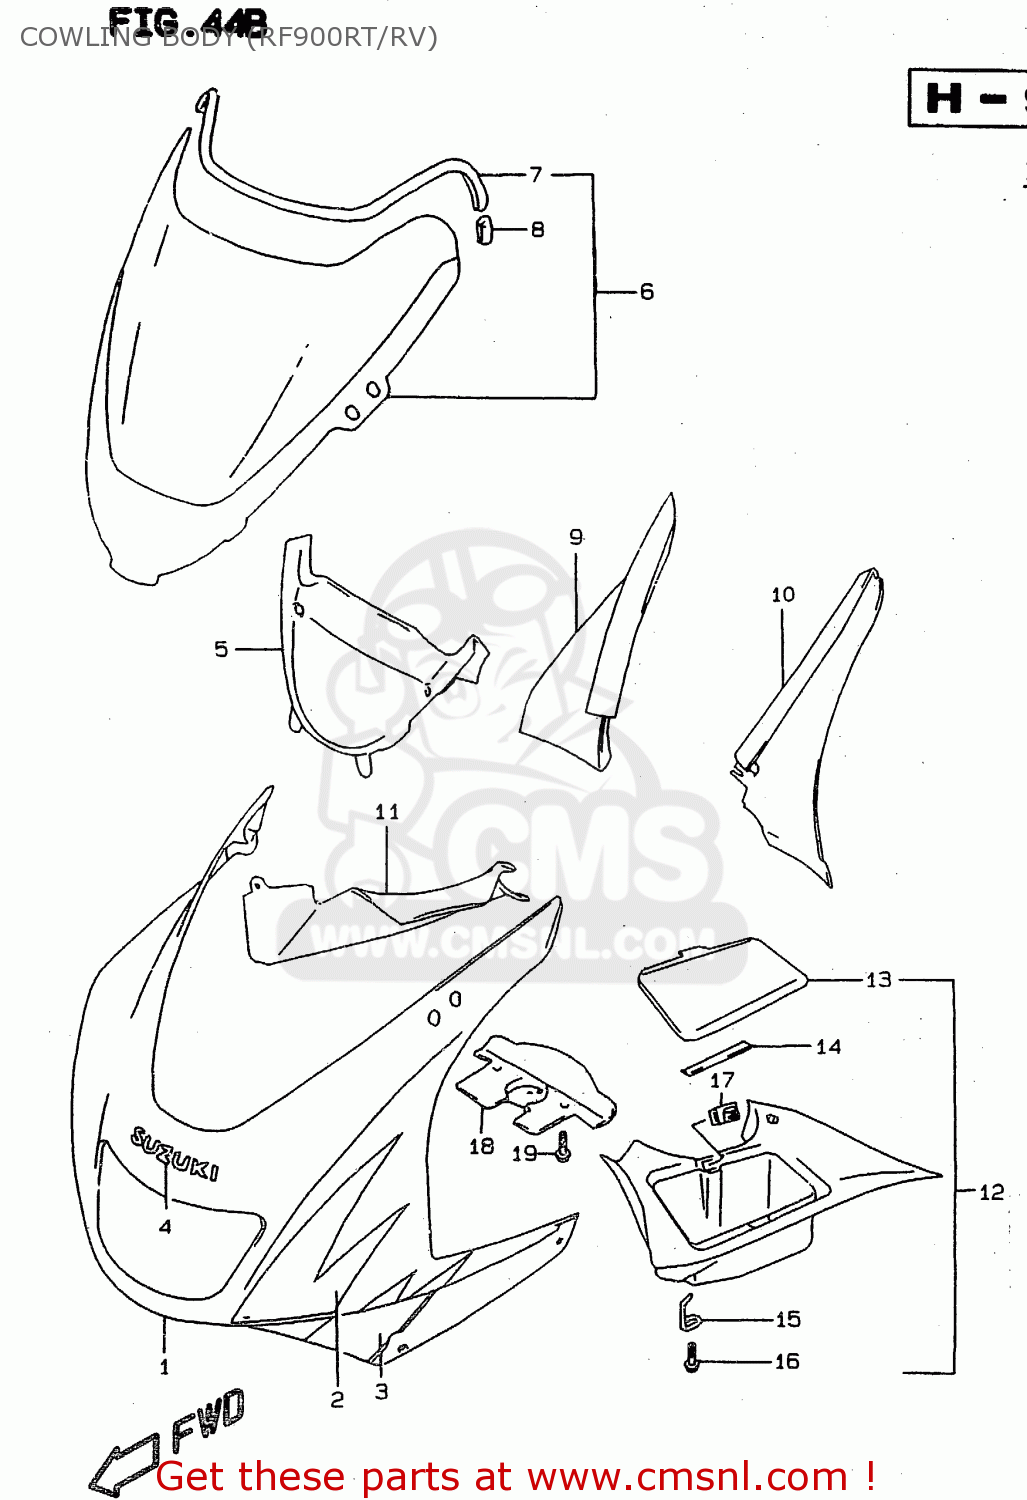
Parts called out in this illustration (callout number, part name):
1	COWLING ASSEMBLY,BODY
2	TAPE SET,BODY FR
3	TAPE SET,BODY SIDE
4	EMBLEM,COWLING UPR
5	PANEL,COWLING CTR
6	WINDSCREEN SET
7	MOLDING WINDSCREEN
8	CLIP,WINDSCREEN MOLDING
9	PANEL,UPR,R
10	PANEL,UPR,L
11	PANEL,SIDE,R
12	PANEL ASSY,SIDE,L
13	LID,PANEL BOX
14	CUSHION,LID
15	HINGE,PANEL LID
16	SCREW
17	LOCK,I/P CTR BOX
18	COVER,COWLING FR LWR
19	BOLT(6X12)
